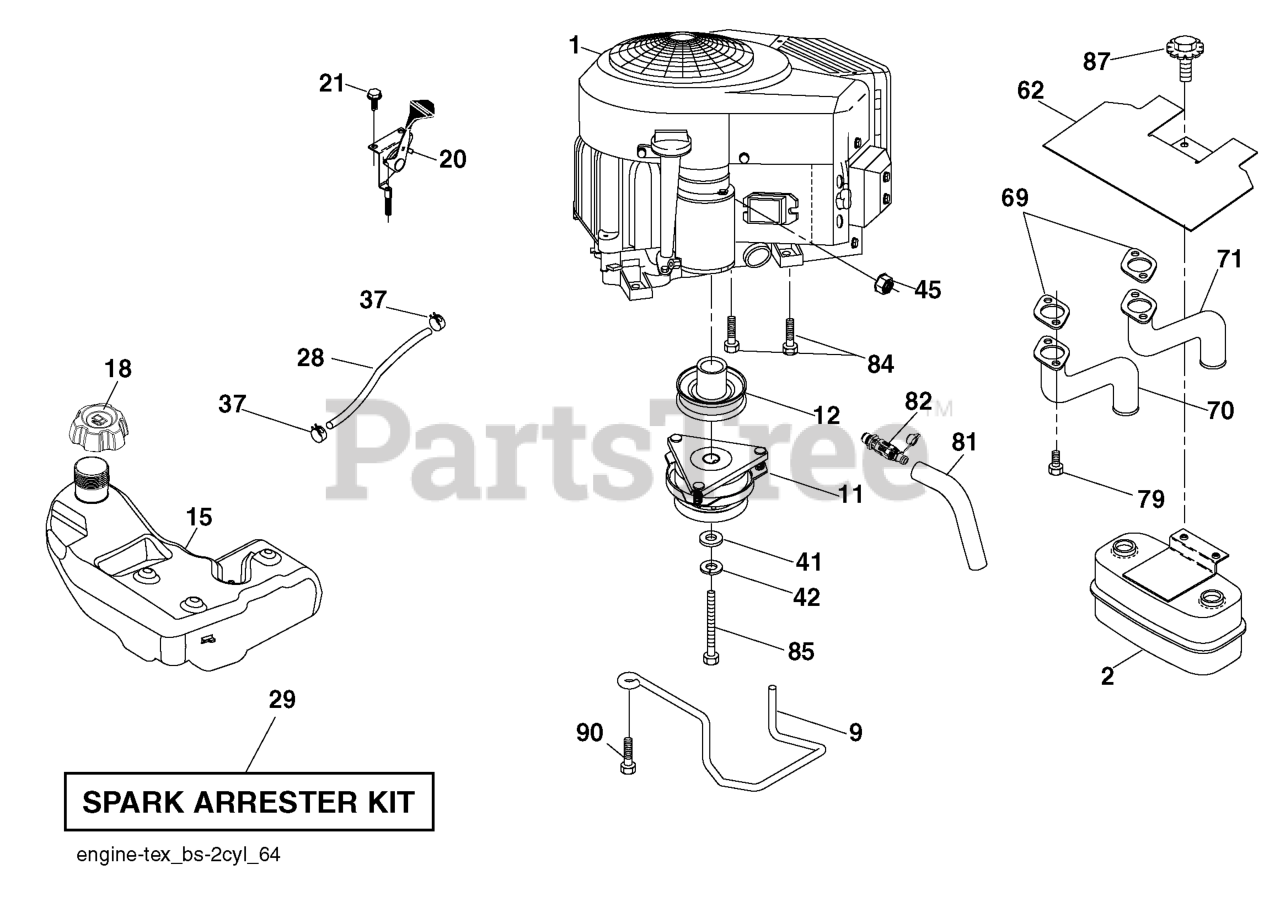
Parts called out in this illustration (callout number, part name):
2	MUFFLER.TWIN.CYL.LOW.TONE
9	KEEPER.BELT.ENGINE.4.2
11	CLUTCH.ELECTRIC.LT.48"*
12	PULLEY.ENGINE.TUFFTORQ
15	TANK.FUEL.SIDE-FILL.3.NON-EPA
18	RP CAP FUEL
20	CONTROL.TH/CK.COBRA.B&S.TWN.BK
21	SCREW.#10 X 0.750.BOS
28	LINE.FUEL.64"REAR.EMIS
29	KIT.SPARK ARRESTOR 794945 B&S
37	HOSE CLAMP
42	LOCKWASHER
45	NUT
62	RP SHIELD HEAT MUFFLER
69	GASKET.MUFFLER
70	RP.EXHAUST.TUBE.LH.BS/TWIN
71	EXHAUST.TUBE.RH.BS/TWIN
79	SCREW.SOCKET.HEAD.5/16-18
81	TUBE, DRAIN OIL ASM.
82	VALUE.OIL.DRAIN
84	SCREW.3/8-16
85	BOLT HEX 7/16-20X4-1/4"
87	BOLT.5/16-18UNCX3/4 W/SEMS.BLK
90	SCREW 3/8-16X1
